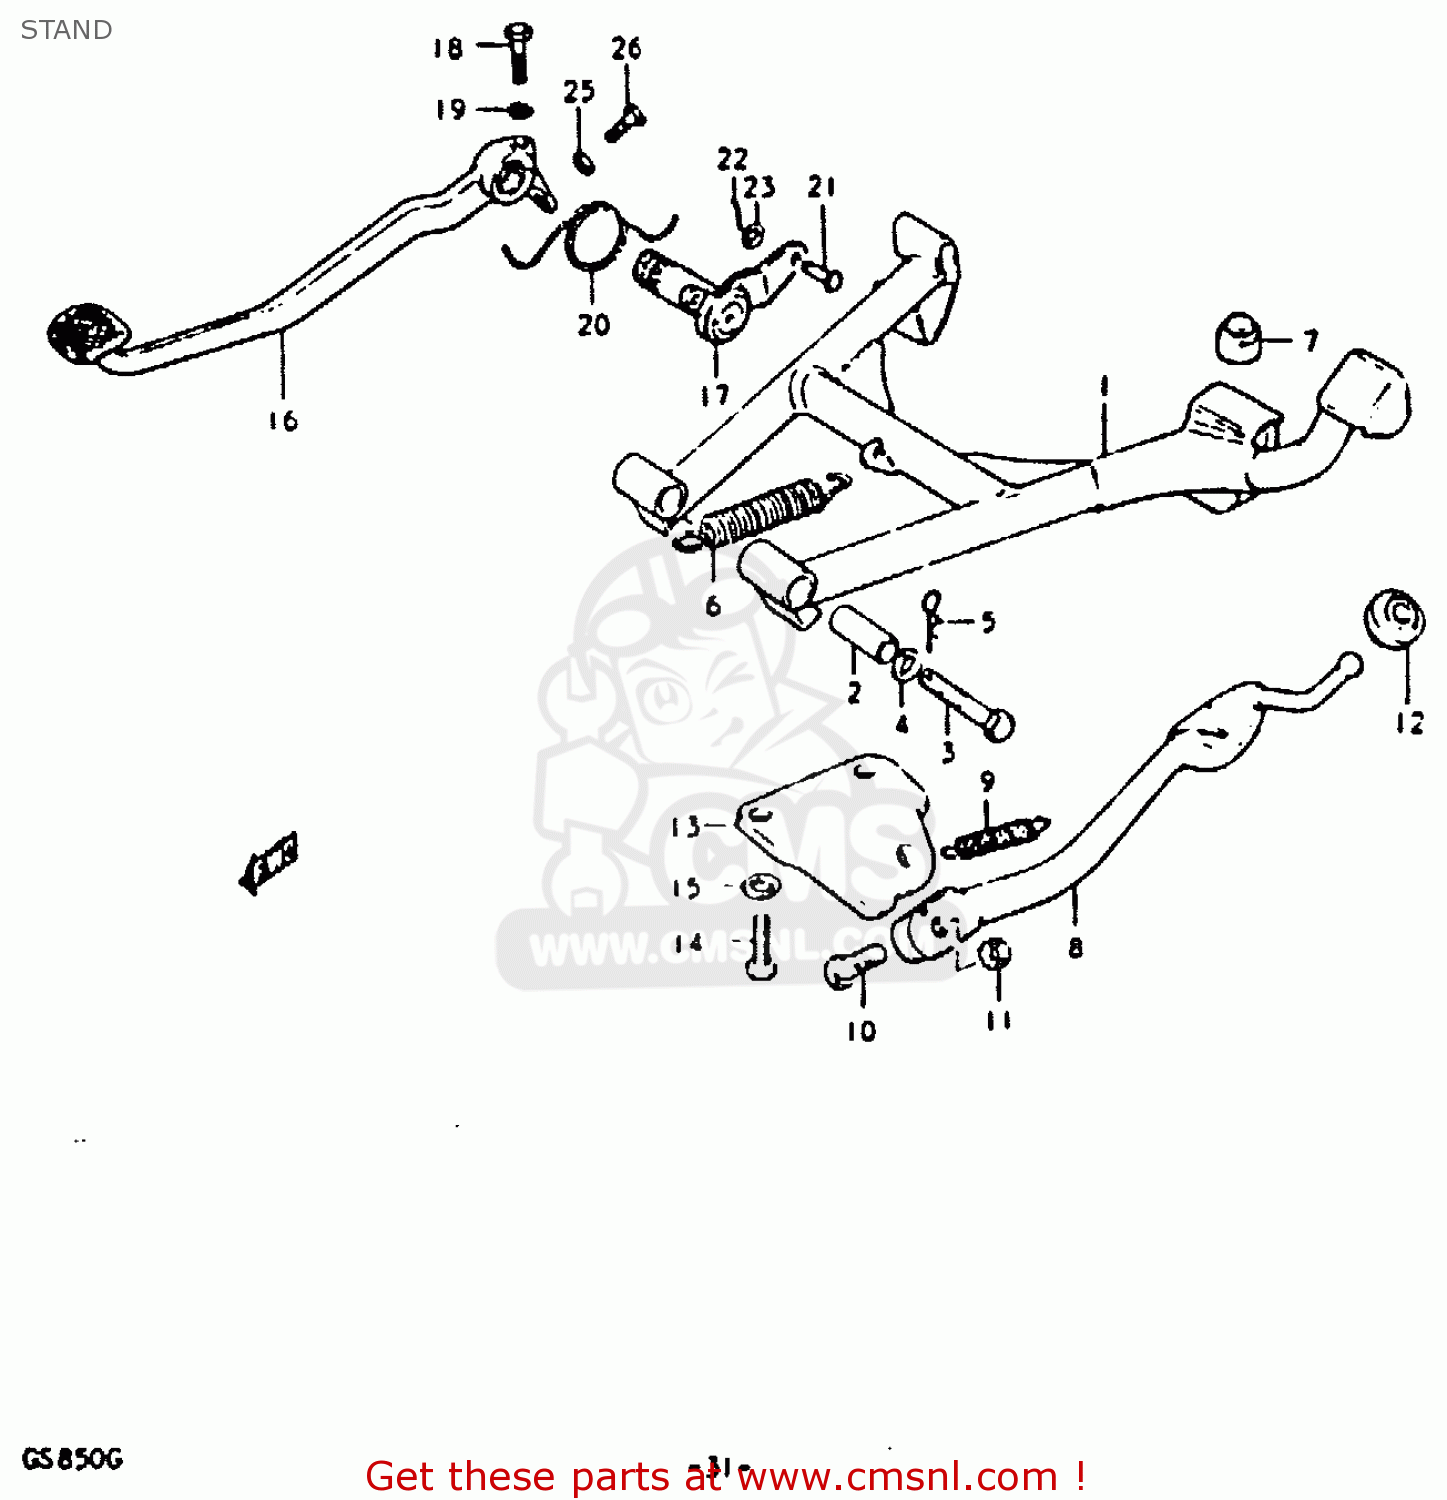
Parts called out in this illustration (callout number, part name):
1	STAND,CENTER
2	SPACER(10X16X38.8)
3	BOLT
4	LOCK WASHER
5	CLIP
6	SPRING
7	CUSHION
8	STAND,PROP
9	SPRING
10	BOLT(10X30)
11	NUT
12	CUSHION
13	BRACKET,SIDE STAND
14	BOLT
15	LOCK WASHER
16	PEDAL,BRAKE
17	ARM,BRAKE PEDAL
18	BOLT
19	LOCK WASHER
20	SPRING
21	PIN
22	PIN
23	WASHER
24	BOLT
25	NUT
